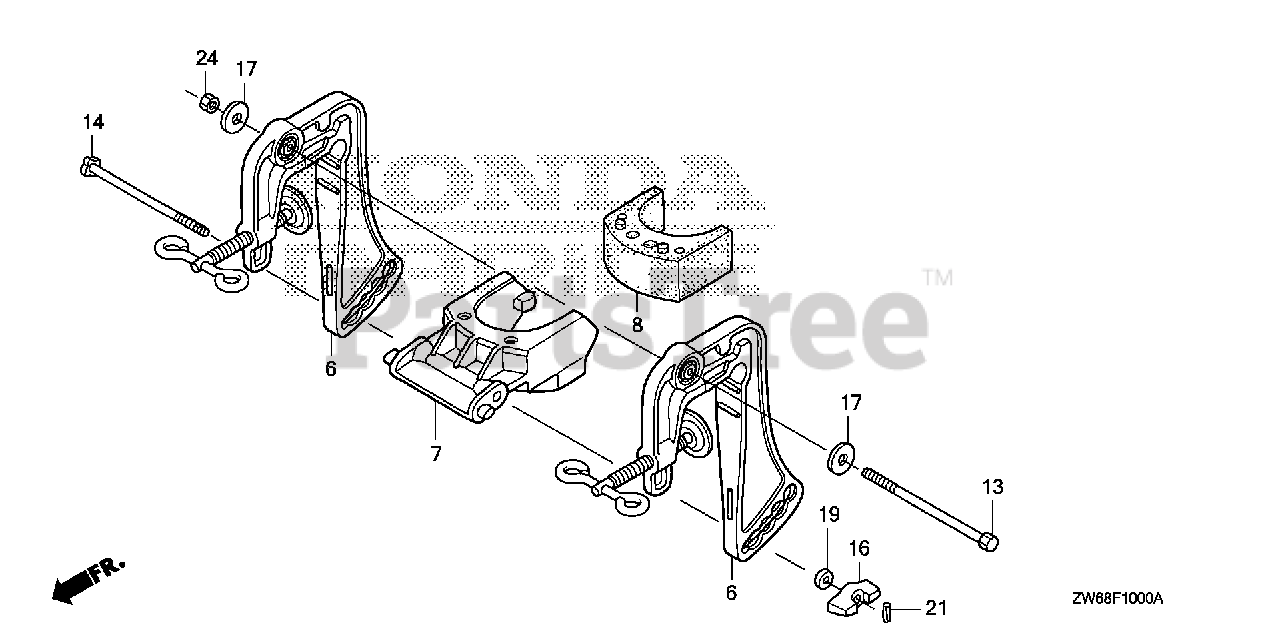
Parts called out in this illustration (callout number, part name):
1	CASE, SWIVEL *NH246* (LOOSY GRAY)
2	CAP, SWIVEL CASE *NH246* (LOOSY GRAY)
3	COLLAR, SWIVEL CASE
4	BLOCK, FRICTION
5	SPRING, FRICTION ADJUSTING
6	BRACKET, STERN *NH246* (LOOSY GRAY)
7	RECEIVER, THRUST
8	RUBBER, THRUST
9	COLLAR, DISTANCE
10	ARM, TILT LOCK
11	SPRING, TILT LOCK
12	BOLT, SWIVEL CASE
13	BOLT, HEX. (8X110)
14	BOLT, DIAMOND (6X110)
15	BOLT, FLANGE (8X35)
15	BOLT, HEX. (8X40)
16	WINGNUT
17	WASHER, PLAIN (8MM)
18	WASHER, PLAIN (8MM)
19	WASHER, PLAIN (6MM)
20	WASHER, PLAIN (8MM)
21	PIN, SPRING (2.5X8)
22	PIN, SPRING (2.5X20)
23	NIPPLE, GREASE
24	NUT, HEX. (8MM)
